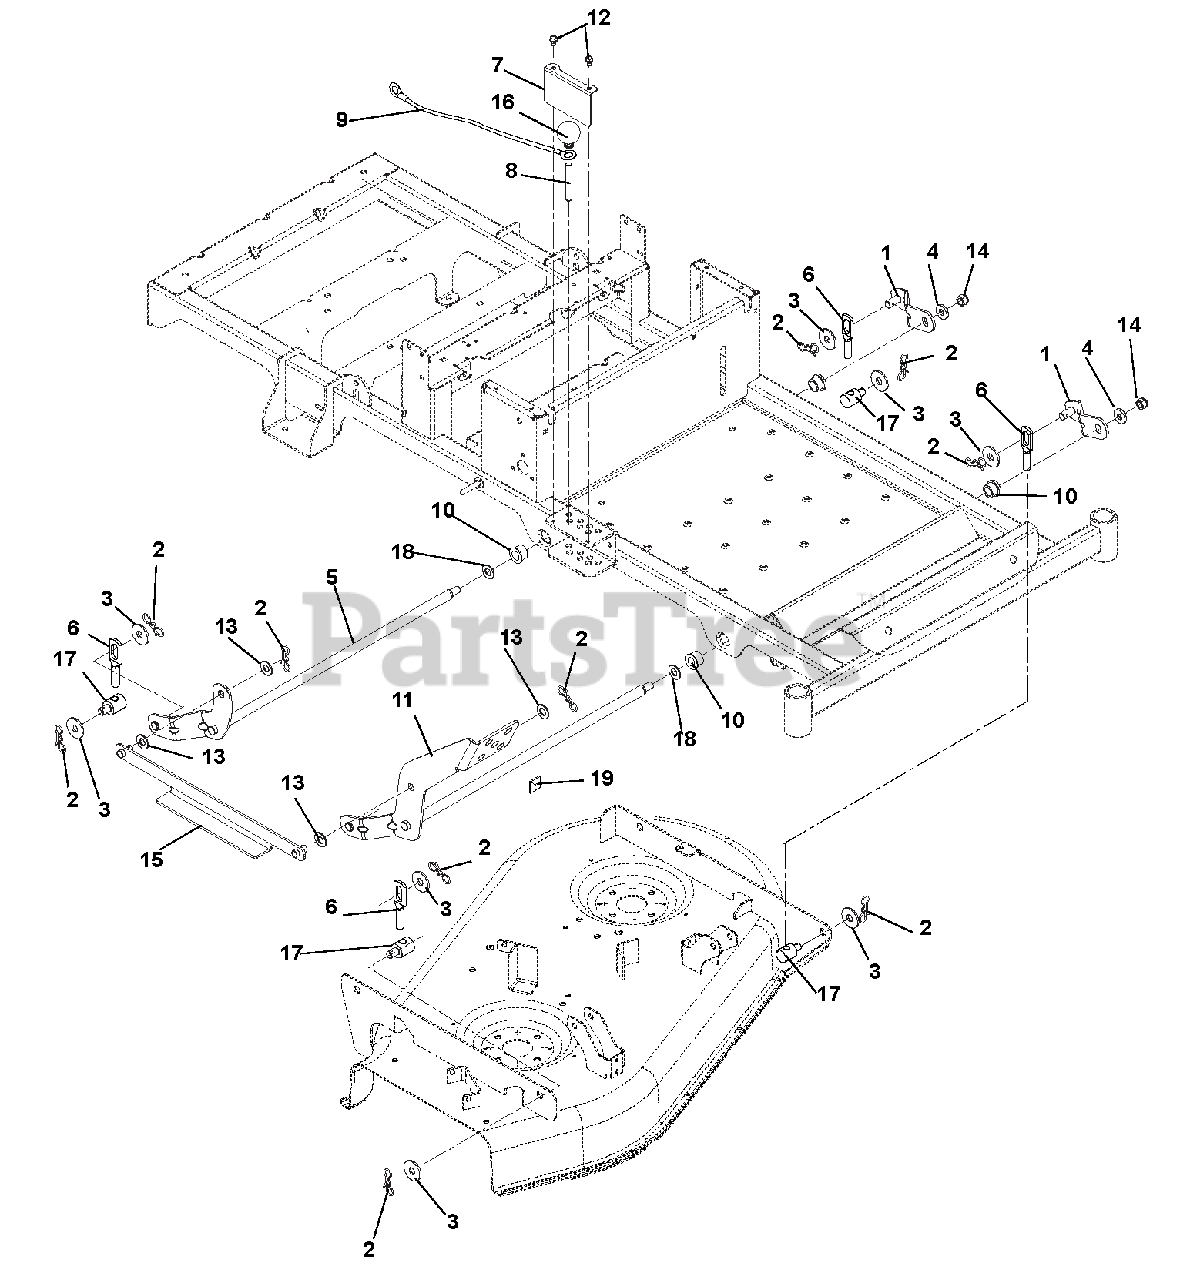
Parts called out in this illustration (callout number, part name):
1	WMT, LIFT ARM
2	PIN,BOW TIE LOCKING .091X1.875
3	WSHR-FL-STL.511X1.441X.125 YWZ
4	WSHR-FL-STL .50X1.25X.160 YWZC
5	WMT, REAR DECK LIFT SHAFT
6	DECK LINK
7	GUARD, DECK LIFT
8	PIN, DECK
9	LANYARD, GALV 12"
10	BSHG-FLG .629X.879X.469X1.250
11	WMT, DECK LIFT PEDAL
12	@SCR-TAP .25-20X.37 HWH YWZ TR
13	WSHR-FL-NYL .518X1.000X.080
14	NUT-LK-NYL .44-20 YWZC
15	WMT, LIFT LINK
16	KNOB,BALL -BLACK 1.47" .375-16
17	TRUNNION-.50
18	@WSHR-FL-STL.656X1.31X.095 YWZ
